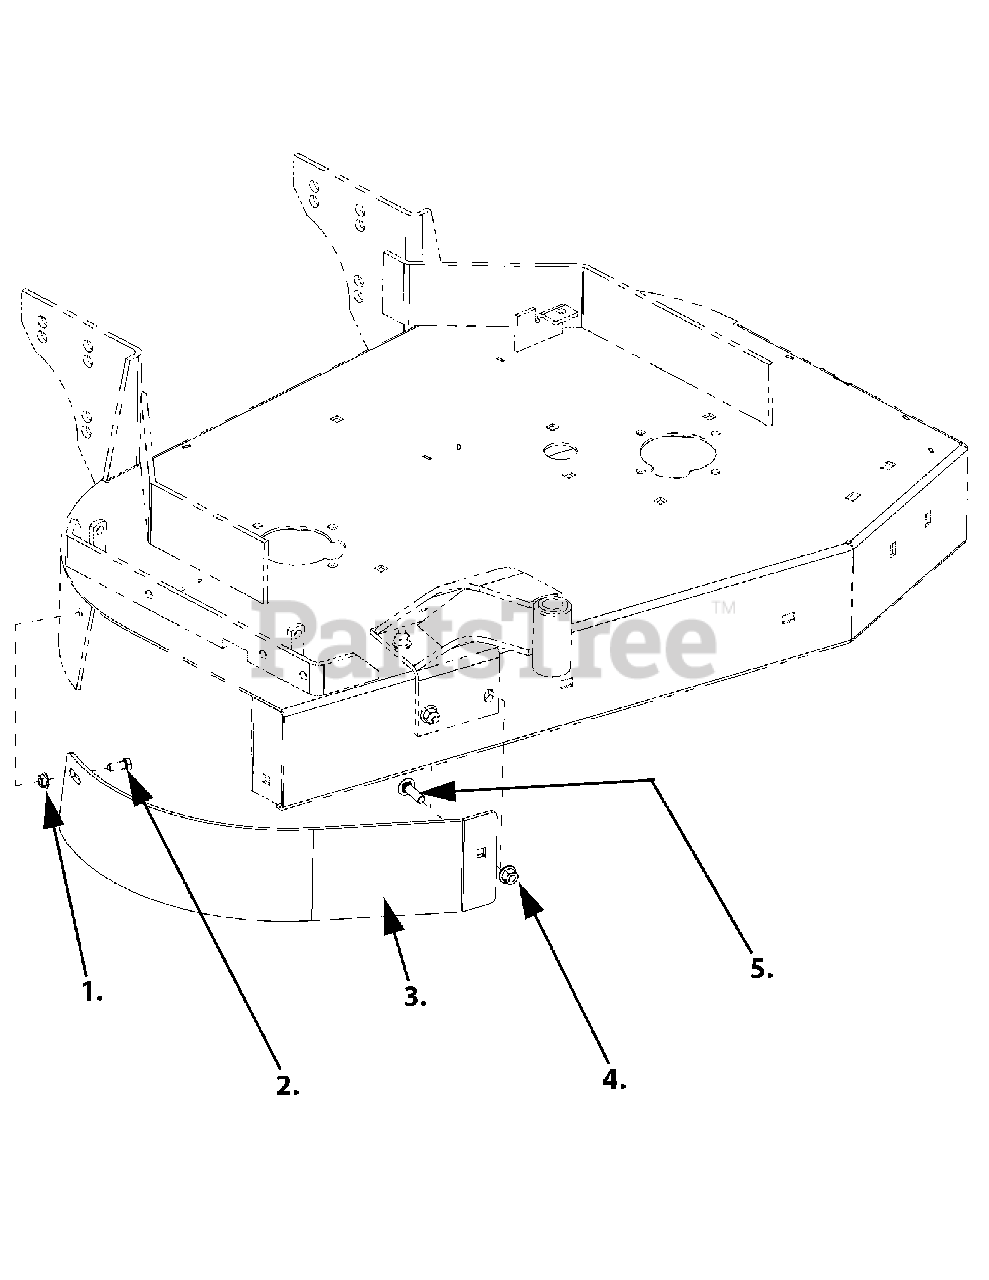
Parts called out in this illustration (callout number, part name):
1	Hex Flange Lock Nut 5/16-18
2	Hex Head CapScrew 5/16-18
3	Mulch Baffle
4	Hex Flange Locknut 3/8-16
5	Carriage Bolt 3/8-16 x 1 1/4
